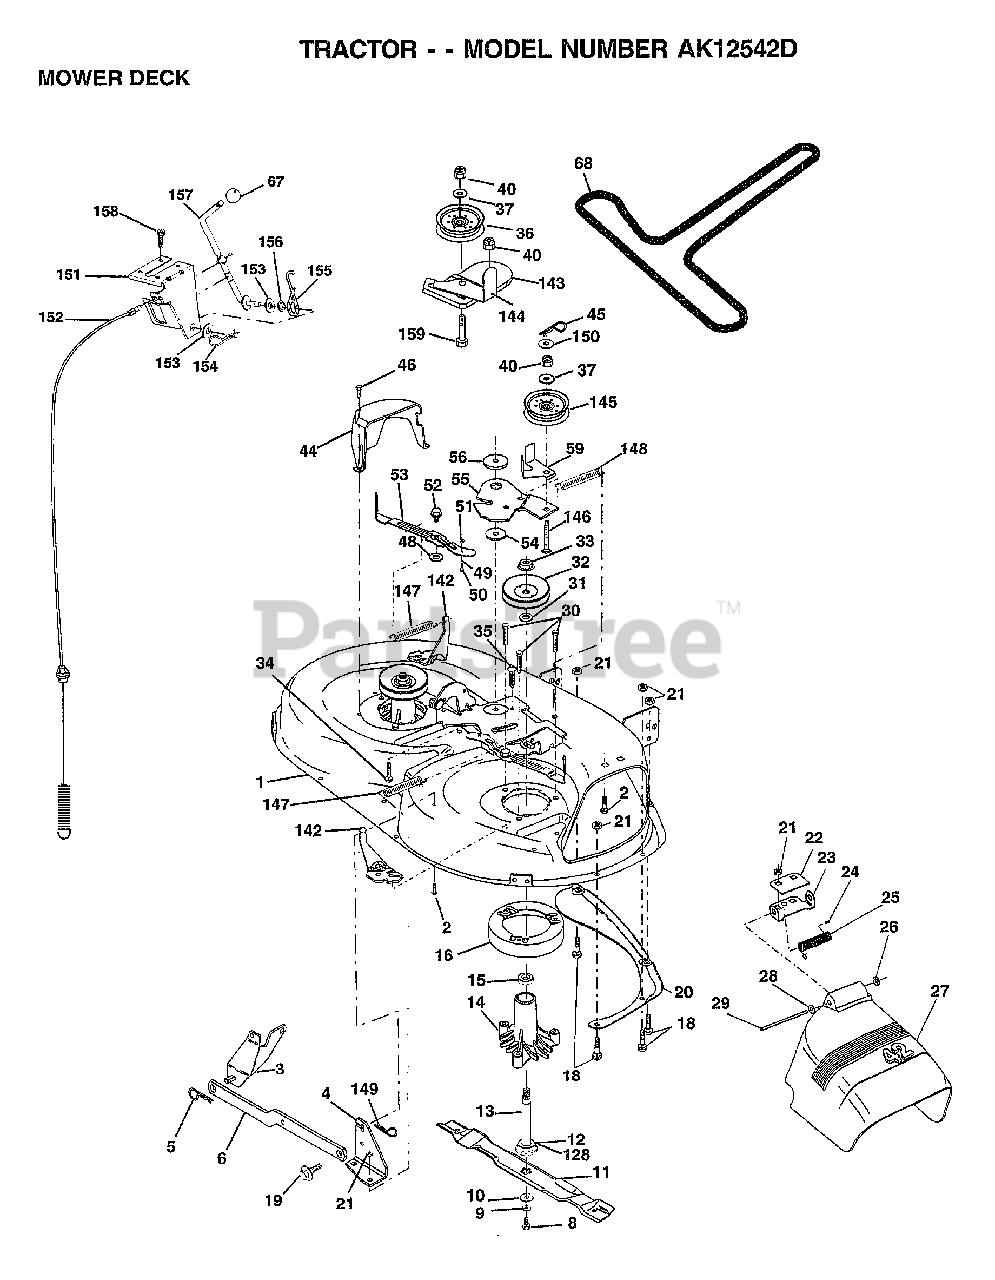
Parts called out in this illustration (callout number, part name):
1	MOWER DECK ASSY
2	BOLT
3	BRKT ASM SWAY BAR
4	BRACKET DECK
8	BLADE BOLT
10	WASHER.HARD.BLADE
11	"BLADE.42"" HIPERF"
12	BEARING.BALL
14	HSG ASM MANDREL
15	BEARING
16	STRIPPER RND MWR
18	BOLT
19	BOLT SHD 5/16-18
20	BAFFLE VORTEX 42
22	STIFFENER BRKT
23	DEFLECTOR BRKT
24	CAP-SLEEVE LT
25	SPRING TORSION
26	NUT PUSH M
27	SHIELD DEFLECTOR 42''
28	WASHER
29	HINGE ROD
30	"SCREW-THD ROLL,WA"
31	WASHER
32	PULLEY.MANDREL.42
34	BOLT
35	XMAS TREE FASTNER
36	FLAT IDLER PULLEY
37	WASHER
44	GUARD MAND LH BLK
45	RETAINER M
46	SCREW.1/4-20X5/8
48	HARD SMALL WASHER
49	ROLLER ASM-CAM
50	SHOULDER BOLT
51	LOCKNUT
52	BOLT.SHLD.5/16-18
53	BRAKE PAD ARM ASM
54	HARDENED WASHER
55	ARM-IDLER
56	SPACER.RETAINER.MOWER
59	GUARD IDLER TUV
67	KNOB T(3/8 HOLE)
68	BELT-V.SEC.46.KEL
128	WASHER.FELT.
142	ARM SPRING BRAKE MOWER
143	BRACKET ARM IDLER
144	KEEPER BELT CLUTCH CABLE
145	PULLEY IDLER FLAT
146	BOLT
147	SPRING EXTENSION
148	SPRING RETURN IDLER
149	RETAINER SPRING
150	WASHER PM
151	BRKT CLUTCH CABLE
152	"CABLE.CLUTCH.42"""
153	WASHER FLAT
154	SPRING RETAINER
155	SPRING RETENTION LVR CLUTCH CAB
156	SPACER
157	ROD.CLUTCH.CABLE.3/8
158	SCREW LT
159	BOLT
